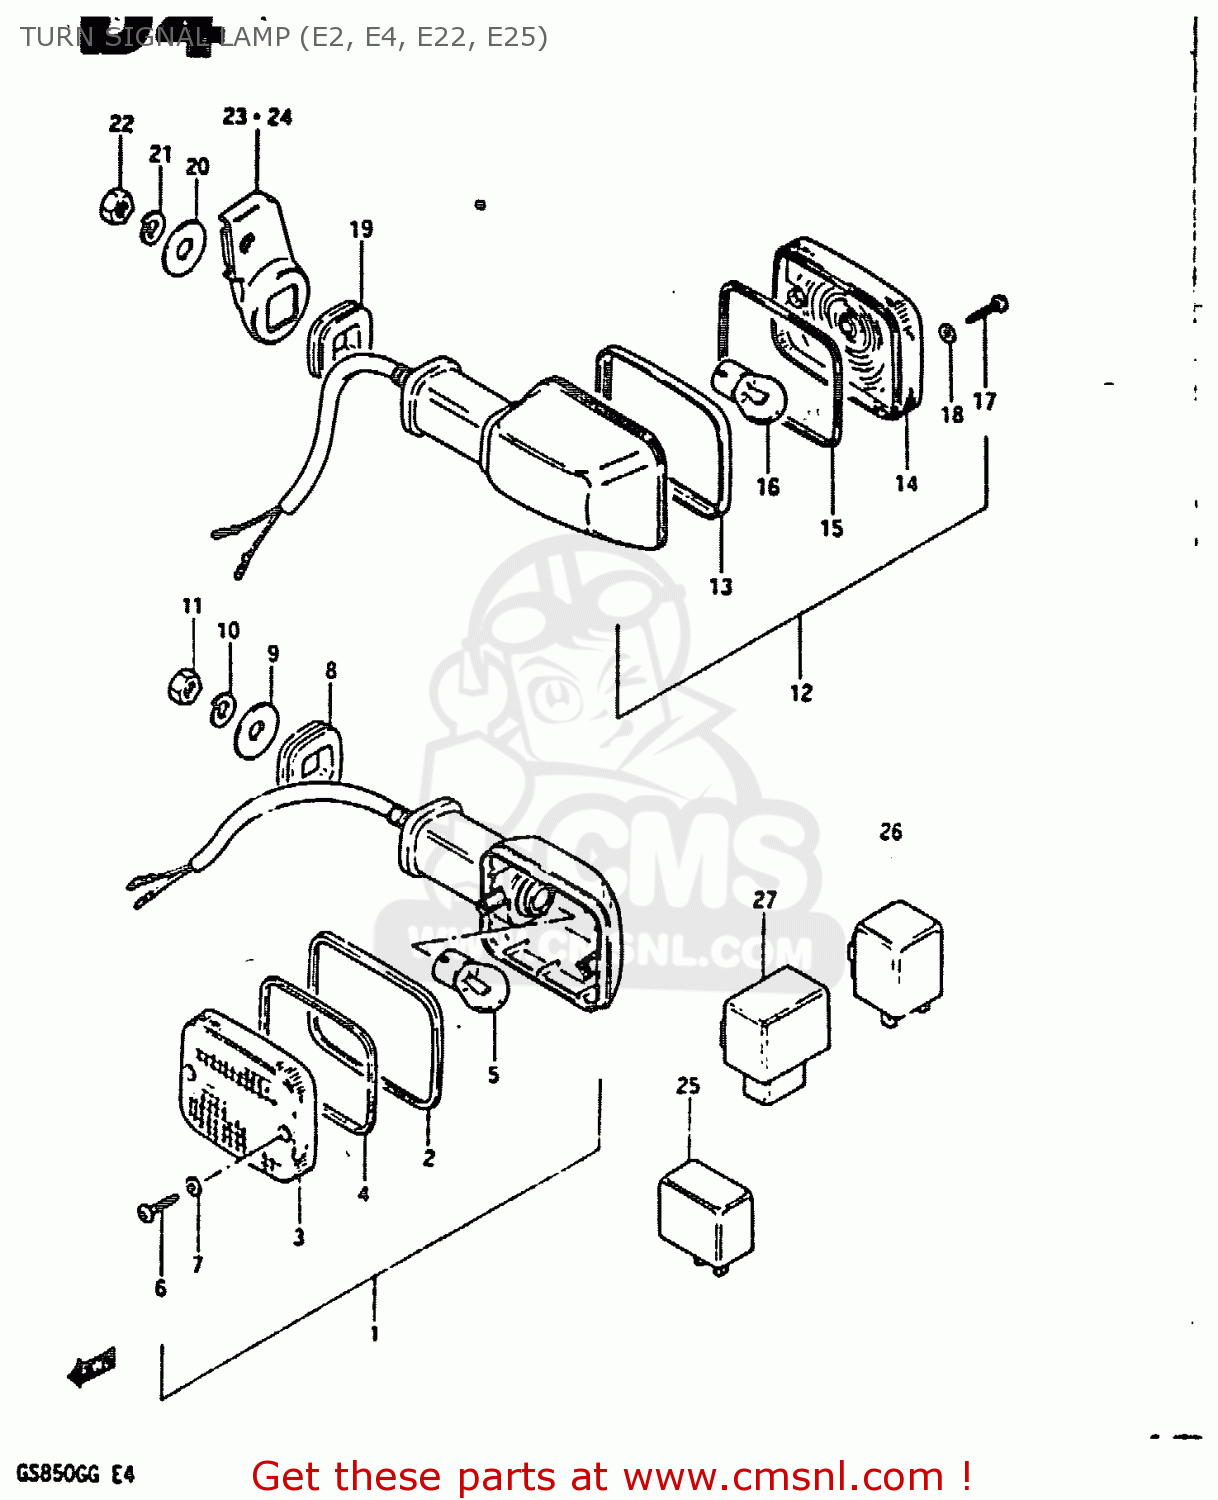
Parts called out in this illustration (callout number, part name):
1	LAMP ASSY, FRONT TURN SIGNAL
2	RIM
3	LENS
4	GASKET (NAS)
5	BULB(12V21W)
6	SCREW
7	GASKET (NAS)
8	CUSHION
9	WASHER (10.5X30X2.3)
10	LOCK WASHER
11	NUT
12	LAMP ASSY, REAR COMBINATION
13	RIM
14	LENS
15	GASKET (NAS)
16	BULB(12V21W)
17	SCREW
18	GASKET (NAS)
19	CUSHION
20	WASHER (10.5X30X2.3)
21	LOCK WASHER
22	NUT
23	BRACKET,REAR TURN SIGNAL
24	BRACKET,REAR TURN SIGNAL
25	RELAY ASSY,TURNSIGNAL
26	RELAY ASSY,TUR
27	UNIT,TURN SIGNAL CONTROL
